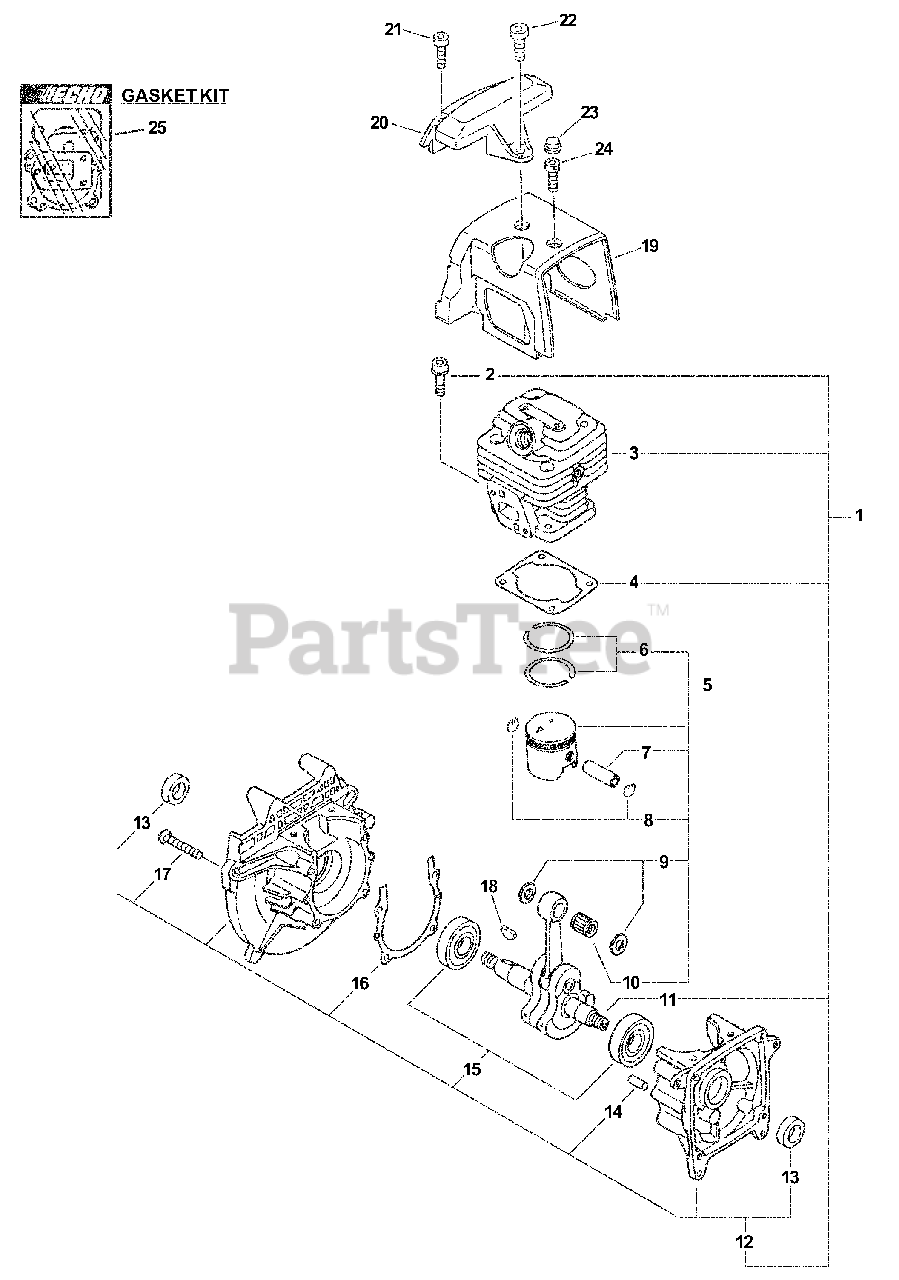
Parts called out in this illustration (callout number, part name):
1	SHORT BLOCK SRM-3400
2	BOLT 5×20
3	CYLINDER
4	GASKET, CYLINDER
5	PISTON KIT
6	RING, PISTON
7	PIN, PISTON
8	RING, SNAP
9	WASHER, THRUST
10	BEARING, NEEDLE 9
11	CRANKSHAFT ASSY
12	CRANKCASE KIT
13	SEAL, OIL 12
14	PIN, LOCATING 4
15	BEARING, BALL - 6201 C3
16	GASKET, CRANKCASE
17	BOLT 5×30
18	KEY, WOODRUFF
19	COVER, ENGINE
20	GUARD, TOP
21	BOLT 4×14
22	BOLT 5×16
23	SCREW - SOCKET HEAD CAP
24	BOLT 5×12
25	GASKET KIT
